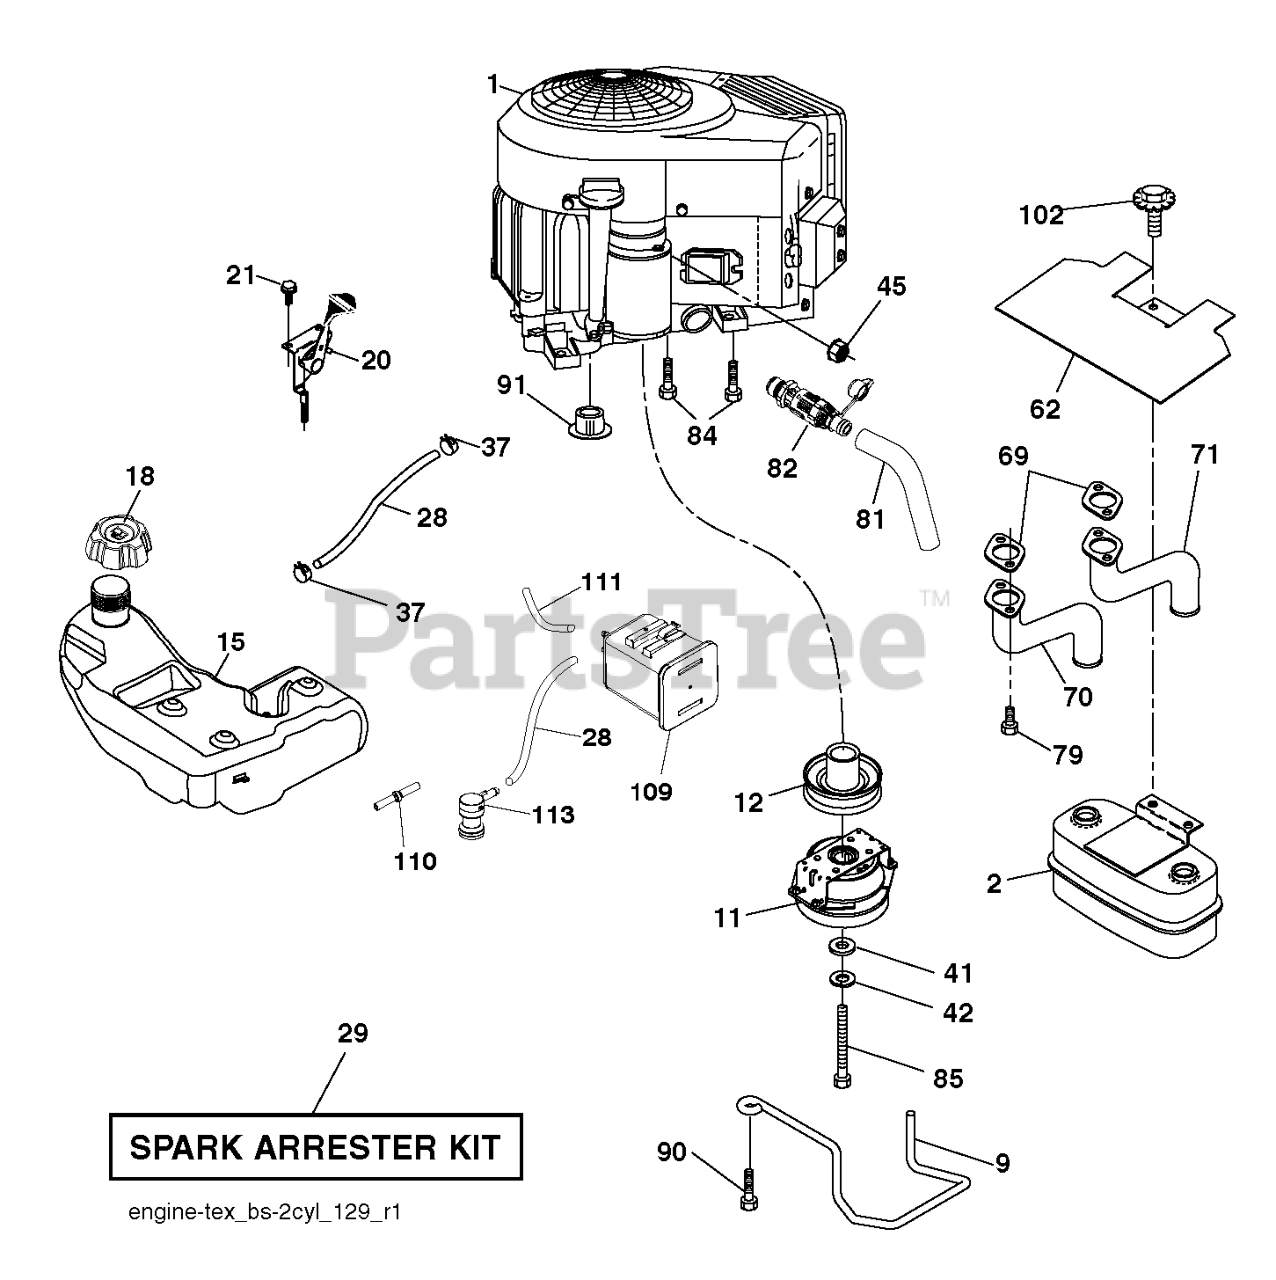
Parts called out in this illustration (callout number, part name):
2	MUFFLER.ASM.TWN.EXTNDED.DFLCTR
9	KEEPER BELT ENGINE
11	CLUTCH.ELECTRIC.LT.48"*
12	PULLEY.ENGINE.TUFFTORQ
15	TANK.ASM.FUEL.3GA.CARB
18	CAP.ASM.FL.RITCH.3"E10.SYM.498
20	CONTROL.TH/CK.COBRA.B&S.TWN.BK
21	SCREW.#10 X 0.750.BOS
28	LINE.FUEL.64"REAR.EMIS
29	KIT.SPARK ARRESTOR 794945 B&S
37	HOSE CLAMP
42	LOCKWASHER
45	NUT
62	SHIELD.HEAT.MUFFLER
69	GASKET.MUFFLER
70	EXHAUST.TUBE.LH.BS/TWIN
71	EXHAUST.TUBE.RH.B&S.TWIN.INTEK
79	SCREW.SOCKET.HEAD.5/16-18
81	TUBE, DRAIN OIL ASM.
82	VALUE.OIL.DRAIN
84	SCREW.3/8-16
85	BOLT HEX 7/16-20X4-1/4"
87	BOLT.5/16-18UNCX3/4 W/SEMS.BLK
90	SCREW 3/8-16X1
91	PARTNER DECAL,
109	CANNISTER, CARBON
110	VALVE.ASM.ANTI-SLOSH
111	PURGE.LINE.36"REAR.CALIFORNIA
113	VALVE.SLANT.CARTRDG.90 DEG.TEX
